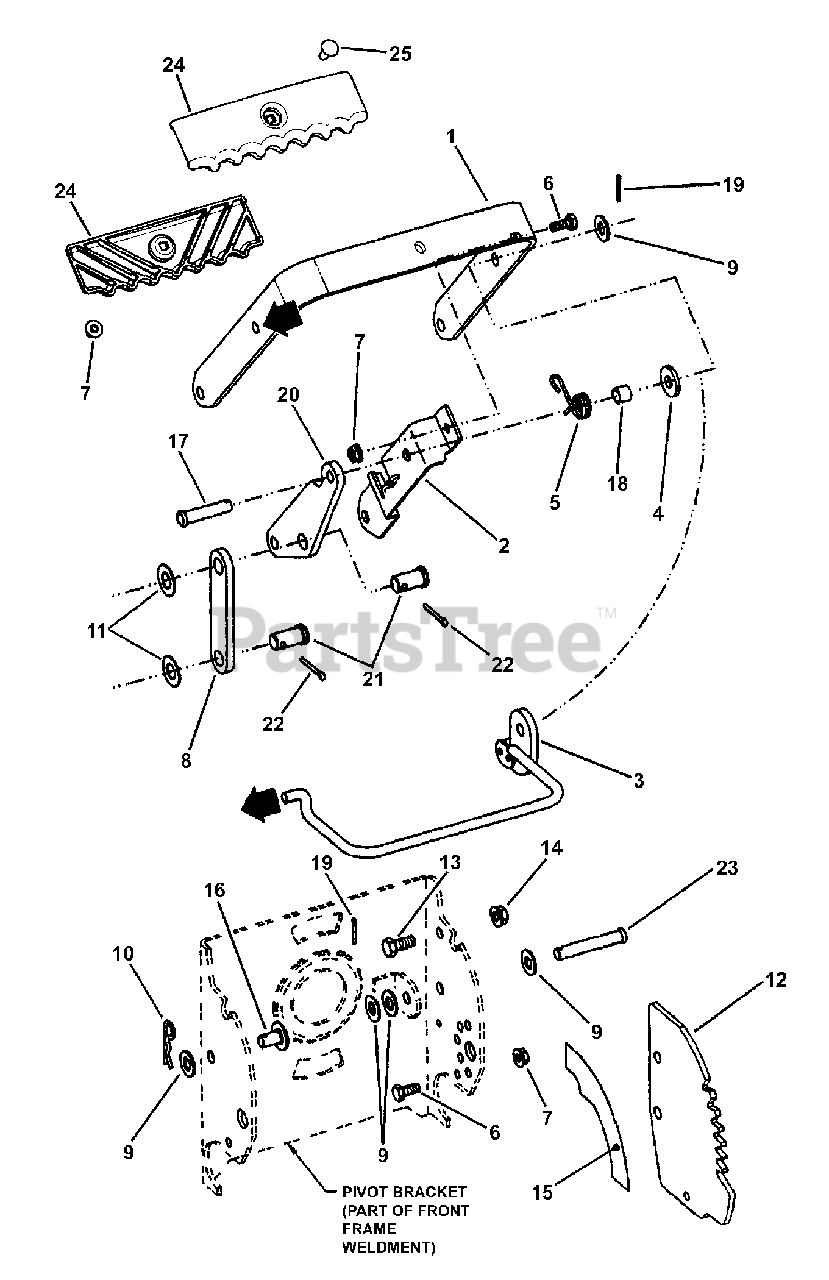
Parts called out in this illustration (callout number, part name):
1	HANDLE, Deck Lift
2	BRACKET, Pivot Support
3	WELDMENT, Deck Lift Handle
4	WASHER - Slipper
5	SPRING, Torsion
6	SCREW, 1/4-20 x 5/8" Hex Head Cap, GR 5
7	NUT, 1/4-20 Hex Flange Lock
8	LINK, Connector
9	WASHER, 3/8" SAE Flat
10	HAIR PIN, 3/32 x 1-1/2"
11	WASHER, 1/2" Flat
12	DETENT, Lift Handle
13	SCREW, 5/16-18 x 3/4" Hex Head Cap, GR 5
14	NUT, 5/16-18 Hex Flange Lock, GR 5
15	DECAL, Deck Position
16	PIN, 3/8 x 1/2" Large Head Clevis
17	PIN, 3/8 x 1-5/8" Clevis
18	SPACER, Deck Lift
19	PIN, 3/32 x 3/4" Cotter
20	PLATE, Connector Arm
21	PIN, 1/2 x .725 Clevis
22	COTTER PIN, 1/8 x 1"
23	PIN, 3/8 x 2" Clevis
24	GRIP, Deck Lift
25	BOLT, 1/4-20 x 3/4" Short Neck Carriage, GR 5
